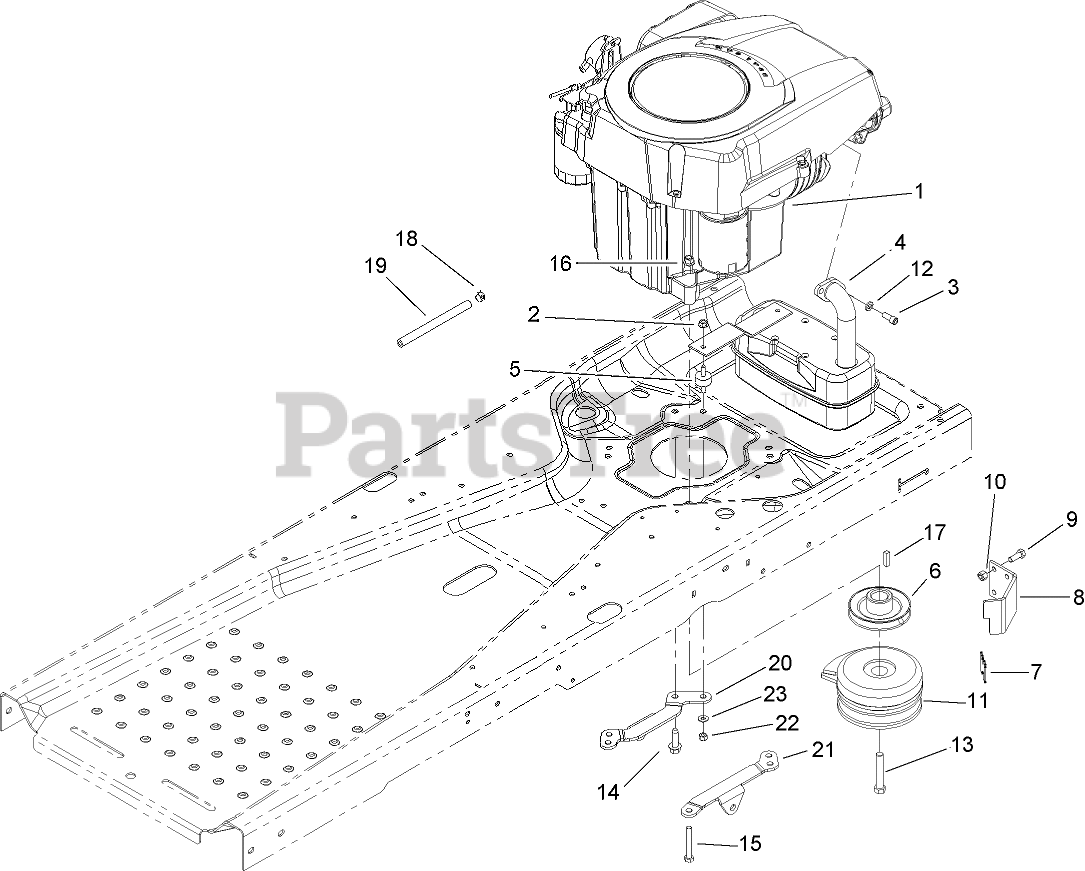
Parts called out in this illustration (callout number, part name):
2	NUT-HF
3	SCREW-HSH
4	MUFFLER-KOHLER
5	ISOLATOR
6	PULLEY-ENGINE
7	BUMPER
8	STOP-CLUTCH
9	SCREW-HH
10	NUT-LOCK, NI
11	CLUTCH-ELECTRIC
12	WASHER-LOCK
13	SCREW-HH
14	SCREW-TAPTITE
15	SCREW-HH
16	NUT-LOCK, NI
18	CLAMP-HOSE
19	HOSE-FUEL
20	SUPPORT-HYDRO, RH
21	SUPPORT-HYDRO, LH
22	NUT-LOCK, NI
23	WASHER-FLAT
